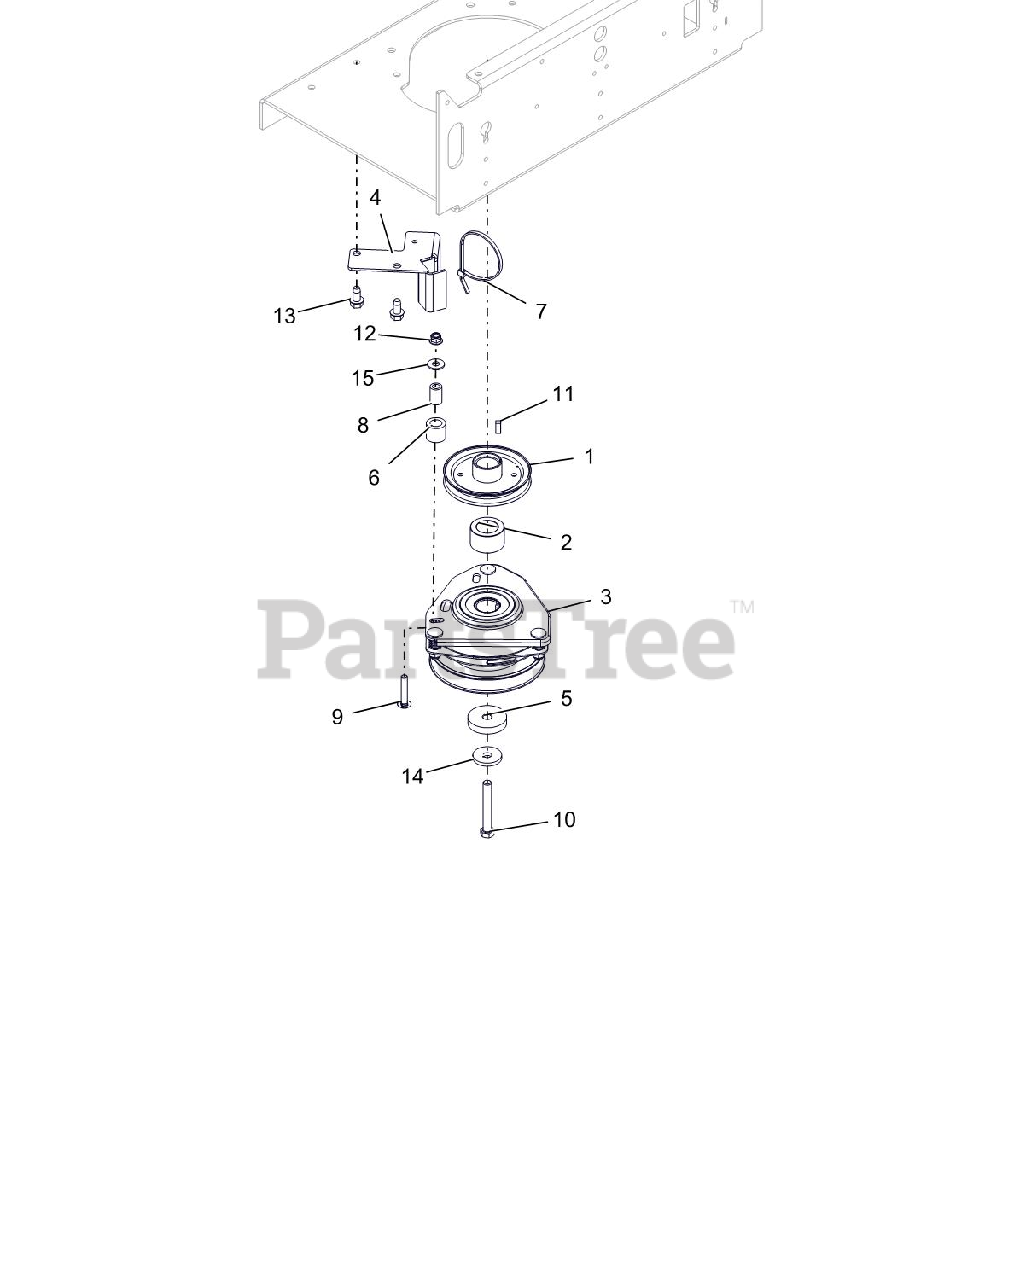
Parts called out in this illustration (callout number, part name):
1	PULLEY, 4.50 OD X 1.127 ENGINE
2	SPACER, 1.125 X 1.750 X 1.06
3	CLUTCH, OGURA GT1A-EH01
4	CLUTCH STOP WLDMT - BLACK
5	SPACER, .450X2.00X.396
6	BUMPER,RUBBER .62X1.0X.88 LG
7	CABLE TIE LG 5-1/2
8	BUSH.,S.391X.622X.950 ST
9	BLT-RDHDSQSHK .31-18X1.75 YWZC
10	BLT-HEX .44-20X3 G8YZ NYTORQ
11	KEY-SQ .25X.625X.25 SAE 8630
12	@NUT-LK-NYL-FLG .31-18 YWZC
13	@SCR-TAP .38-16X.75 HWH TR YWZ
14	WASHER, 7/16" SPRING DISK
15	@WSHR-FL-STL.38X.875X.083 YWZC
